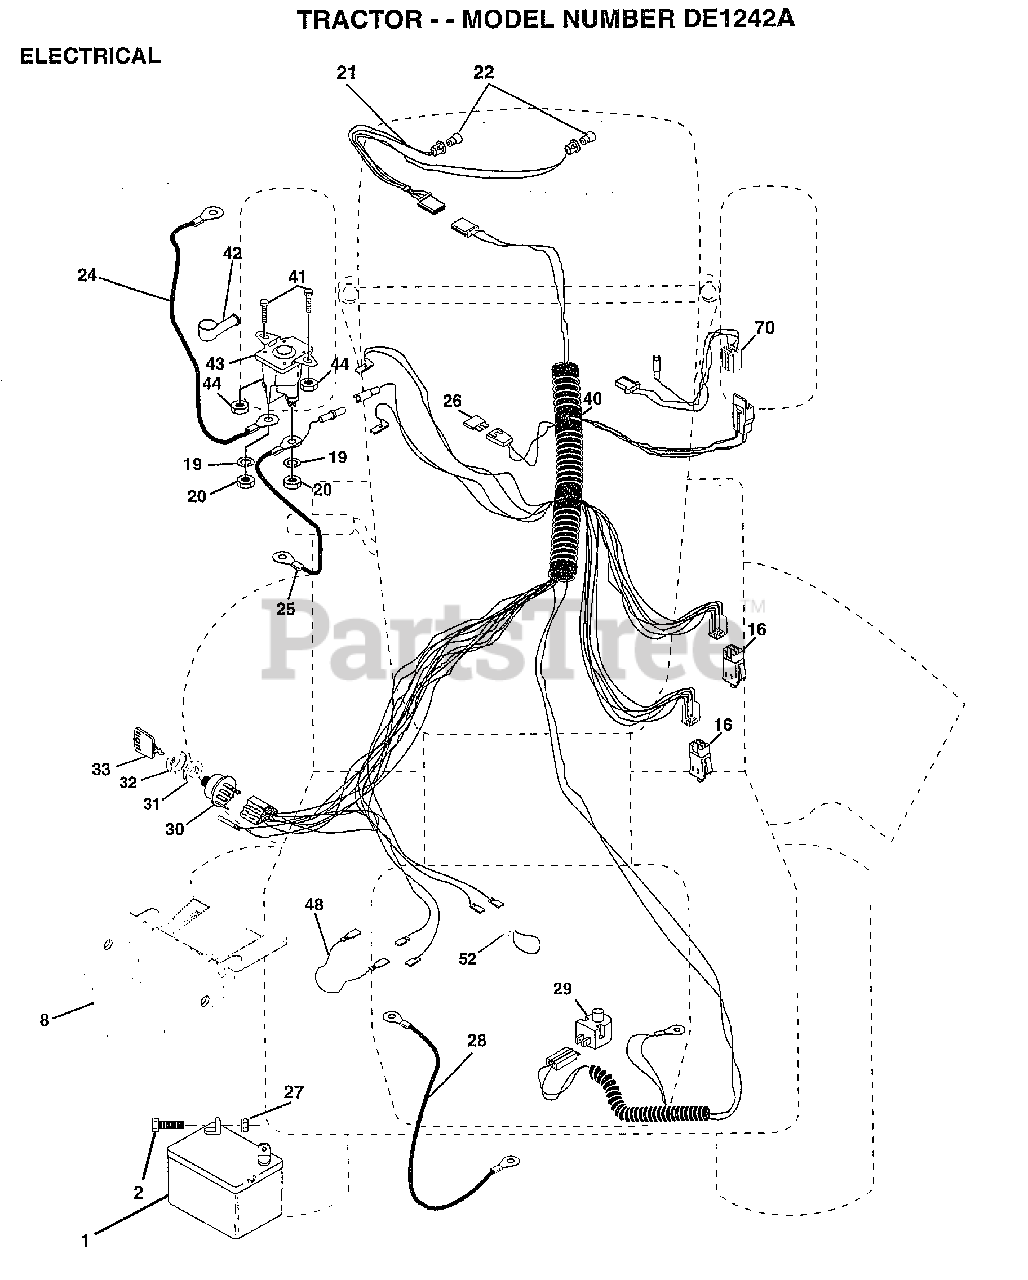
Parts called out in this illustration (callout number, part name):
2	BOLT LT
8	"CASE,BATTERY.MECH"
16	SWITCH INTERLOCK
20	NUT
21	HARNESS.ASM.LIGHT W/4152J
22	HEADLAMP BULB
24	"CABLE T, BATTERY"
25	CABLE.BTRY.6GA.RD
26	FUSE.15 AMP
27	NUT
28	CABLE T
29	SWITCH SEAT
30	SWITCH IGN 4POS
31	NUT IGNITION
32	COVER KEY SWITCH
33	KEY
40	HARNESS.IGNITION
41	BOLT HXHD FIN
44	NUT HXKEP 1/4X20
48	ADAPTER AMMETER
52	PROTECTION LOOP
70	HARNESS.ENGINE
